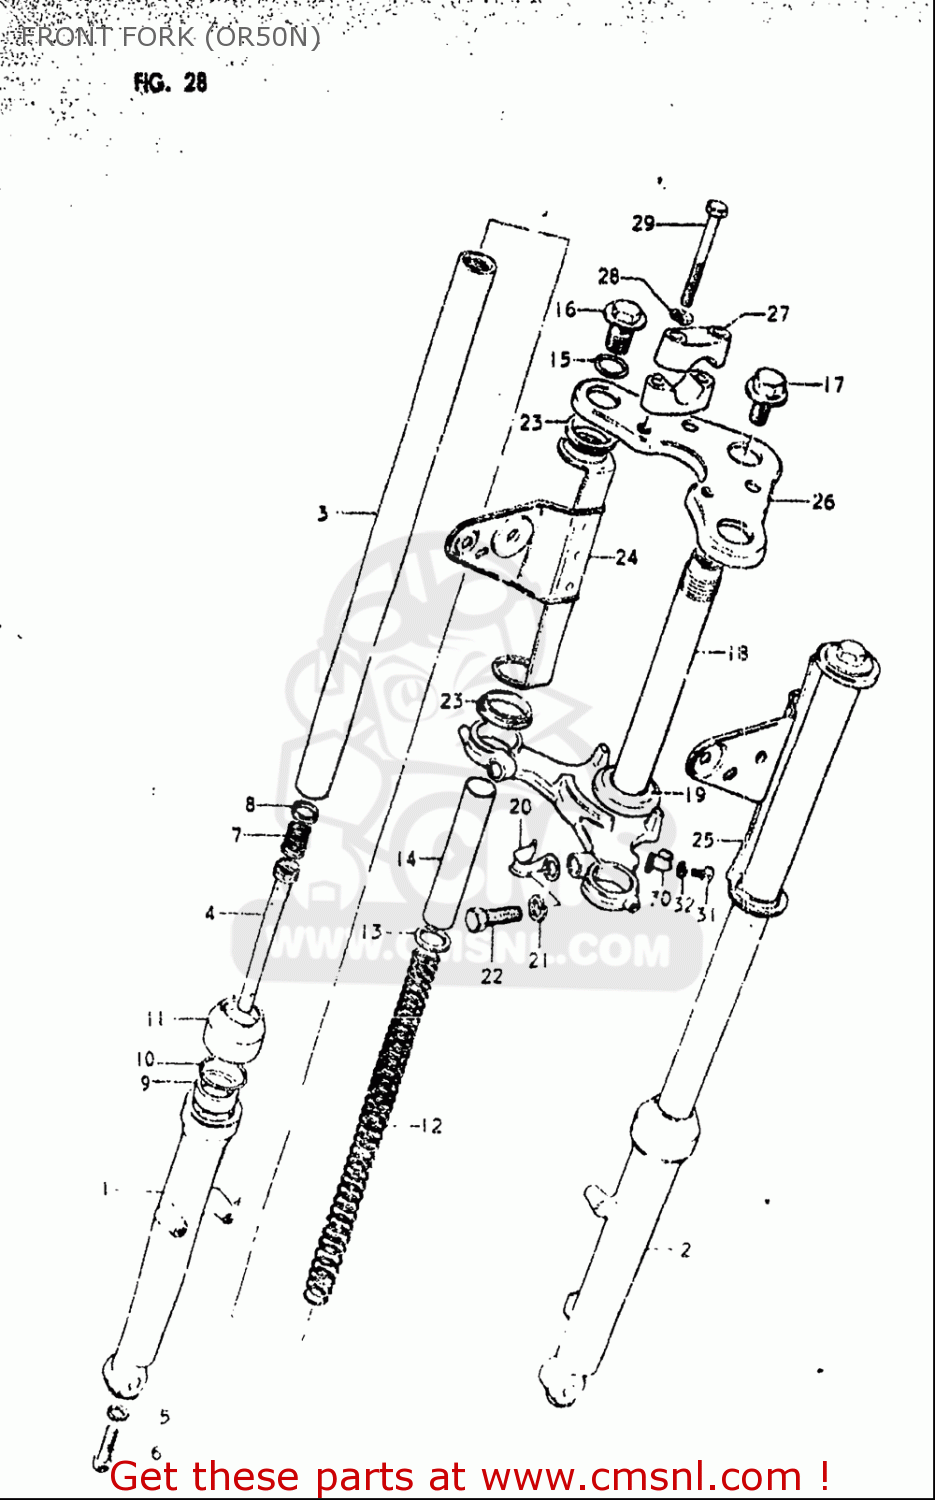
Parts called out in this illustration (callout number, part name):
5	GASKET (NAS)
6	BOLT(8X27)
7	SPRING,REBOUND
8	RING,PISTON
9	SEAL,OIL
10	RING,OIL SEAL STOPPER
11	DUST SEAL
12	SPRING,FRONT FORK
13	JOINT,SPRING
14	SPACER,SPRING
15	O RING(D:2.4,ID:17.8)
16	CAP
17	BOLT
19	RACE,STEERING OUTER LWR
20	CLIP,SPEEDOMETER CABLE
21	WASHER,LOCK
22	BOLT
23	CUSHION
27	HOLDER,HANDLE UPR
28	WASHER,LOCK
29	BOLT
30	CLIP
31	SCREW
32	WASHER,LOCK
